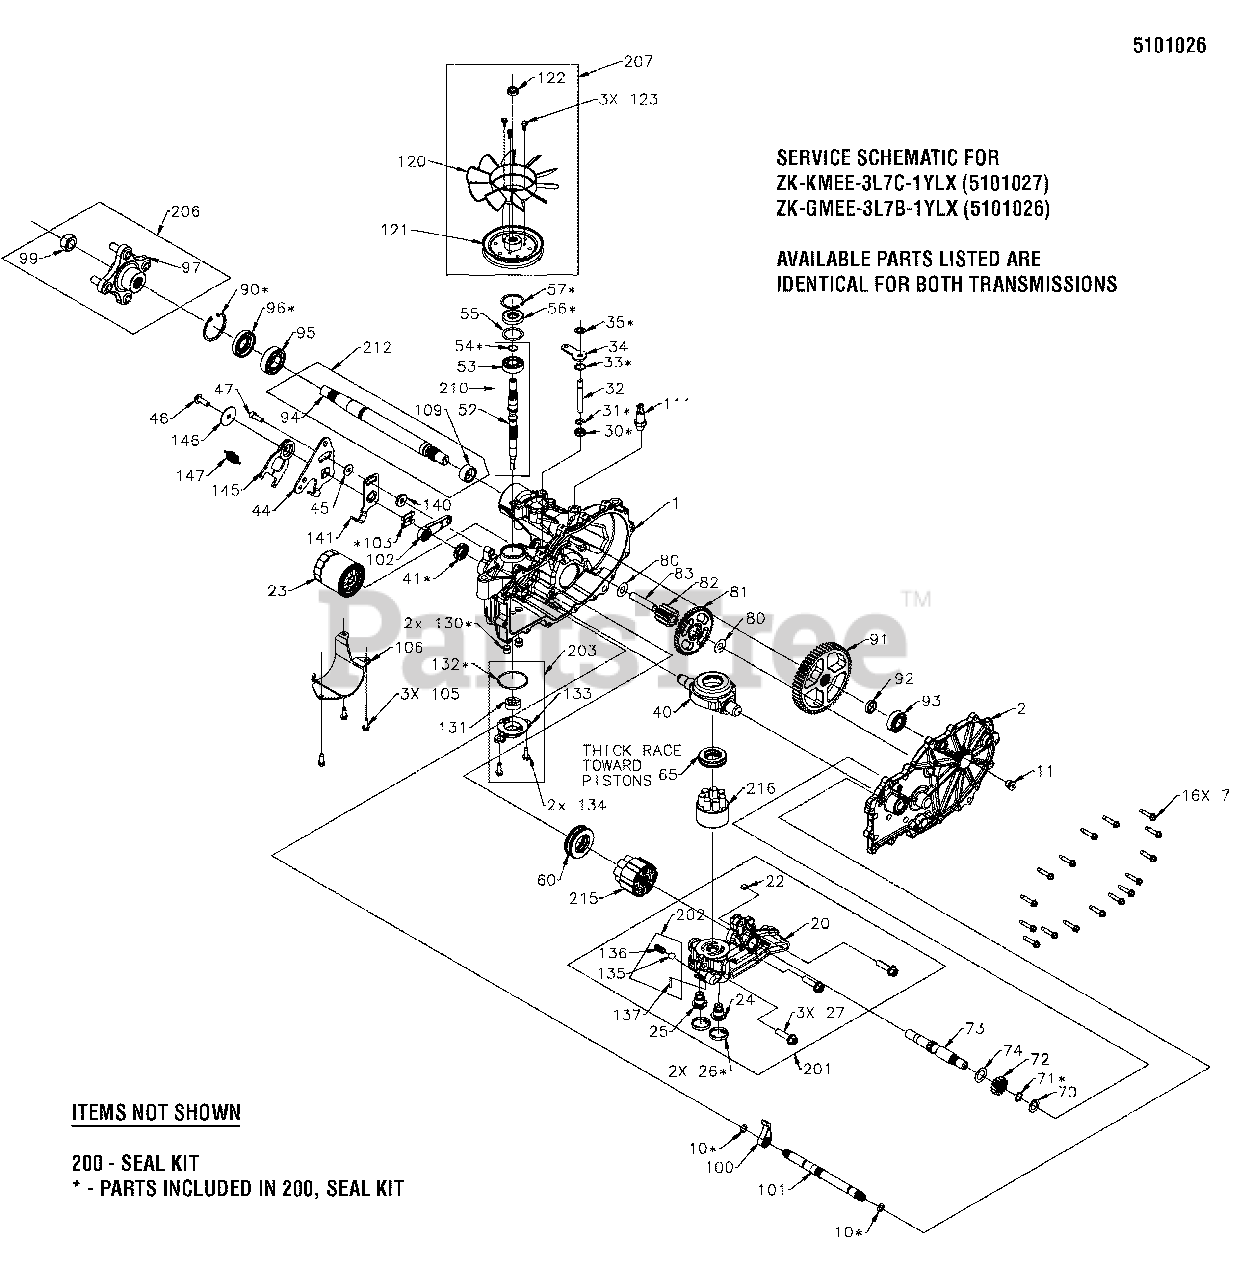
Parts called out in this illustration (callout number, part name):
23	OIL FILTER
41	SEAL, LIP, 18 X 32 X 7
56	SEAL, LIP, 17 X 40 X 7
57	RING, RET 2.06 INT
95	BEARING, BALL, 1.0 X 52 X 15 OPEN 6205M
120	FAN, 7", 10 BLADE
121	PULLEY, 4.5 INCH
200	KIT SEAL
210	KIT, INPUT SHAFT
